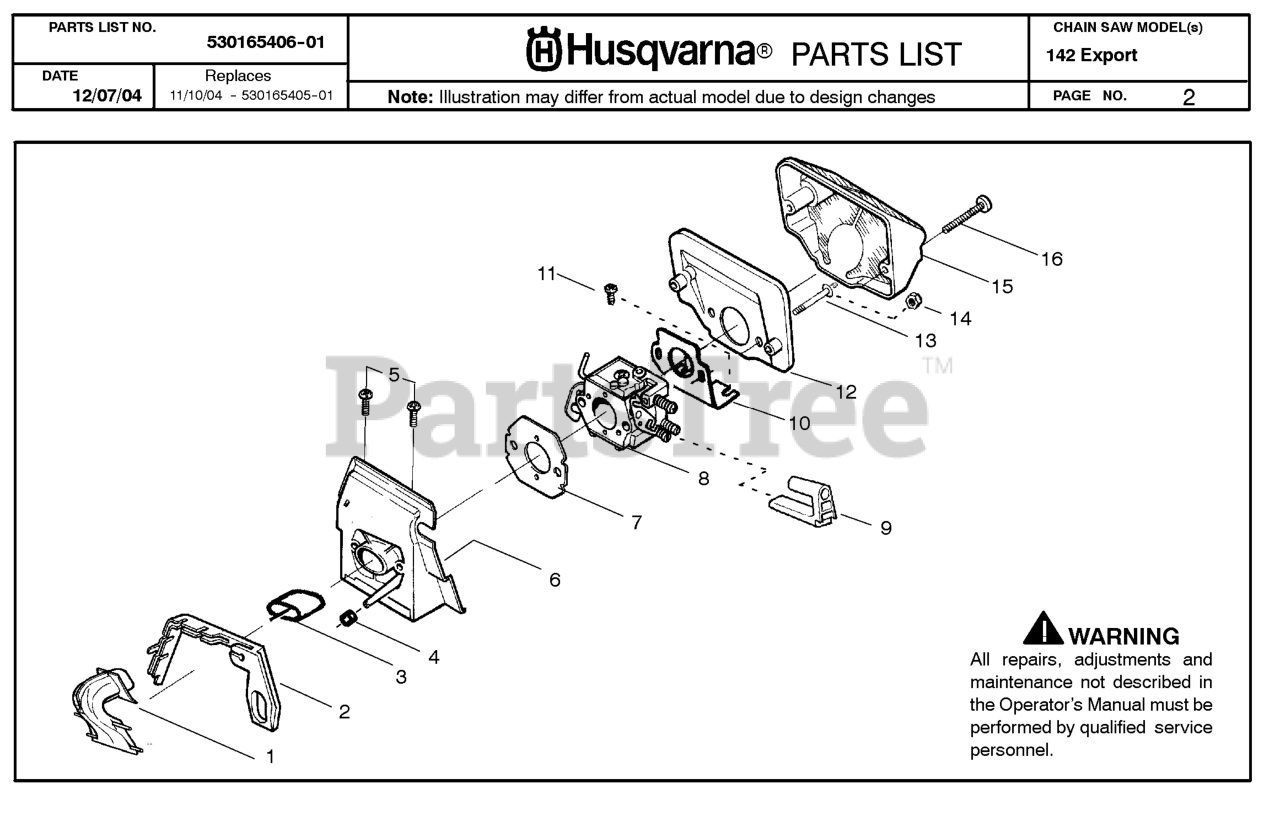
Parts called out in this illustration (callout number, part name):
1	INTAKE HORN
2	TURBO CLEAN SEAL
3	INTAKE PIPE
4	IMPULSE PIPE
6	CARB ADAPTOR
7	GSKT,CARB 36/41
8	CARBURETOR W-29
12	AIR FILTER (BOTTOM)
13	STUD-CARBURETOR
15	AIR FILTER
